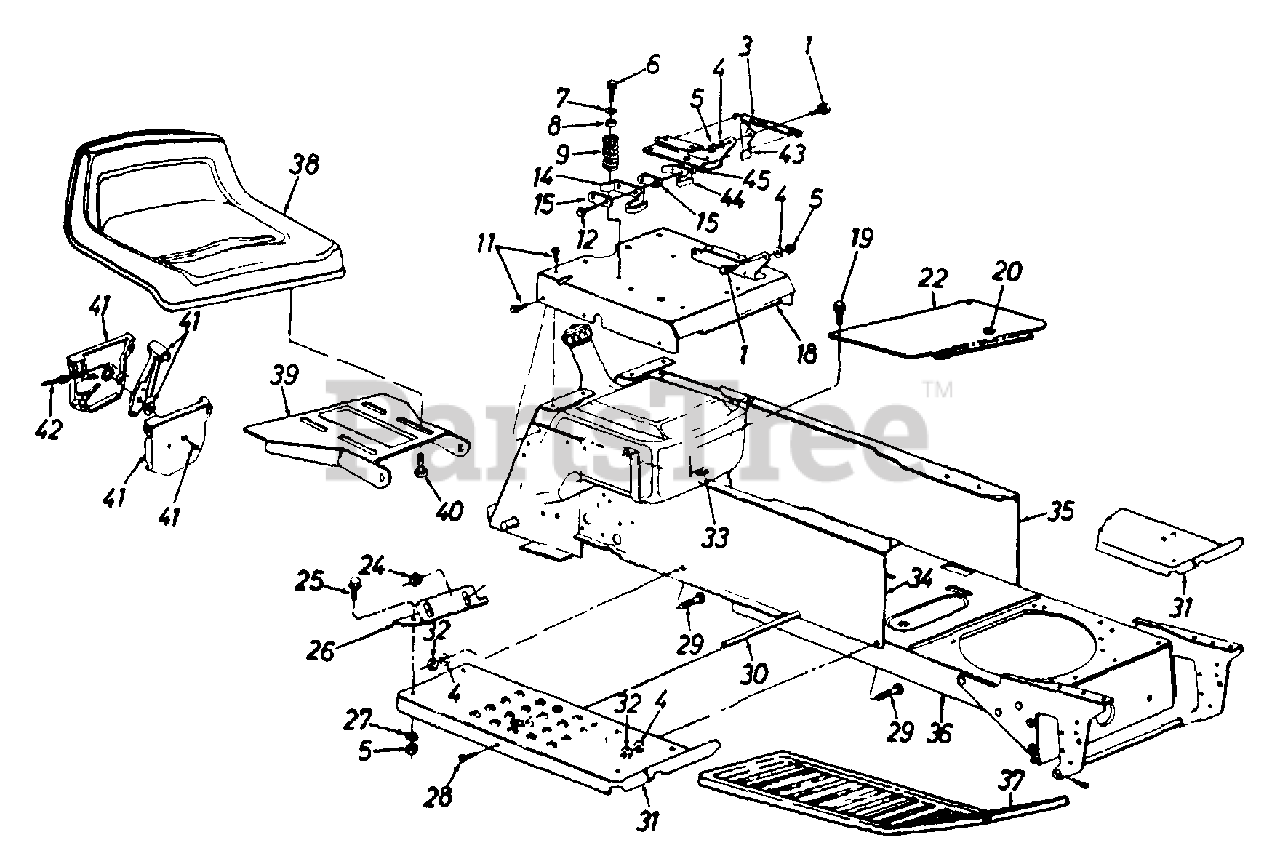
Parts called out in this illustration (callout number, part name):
1	Shld. Bolt .437" Dia. x .162"
3	Ext. Spring 5.31" Lg.
4	L-Wash. 5/16" I.D.
5	Hex Nut 5/16-18 Thd. (Gr. 5)
6	Hex Wash. Hd Tap Scr. 5/16-18 x .7"
7	Fl-Wash. .344" I.D.
8	Bushing
9	Compression Spring
11	Hex Wash. Hd. AB-Tap Scr. 5/16 x .75
12	Hex Wash. Hd. AB-Tap Scr. #8 x .5"
14	Spring Switch
15	Insulator Plate
18	Seat Plate
19	Truss Mach. B-Tap Ser. #10 x .5" Lg.
20	Snap Bushing
25	Hex Bolt 5/16-18 x .75" Lg.
28	Truss Mach Scr 5/16-18 x .75" Lg.
29	Rib Neck Bolt 5/16-24 x .75" Lg.
30	Running Board Rod
33	Speed Nut #10Z
38	Seat
40	Hex Tap Scr. 3/8-16 x .62" Lg.
41	Throttle Control Box Ass'y
42	Throttle Control Wire 35" Lg.
43	Seat Lift Bracket
44	Seat Spring Switch
45	Insulator Boss Plate
